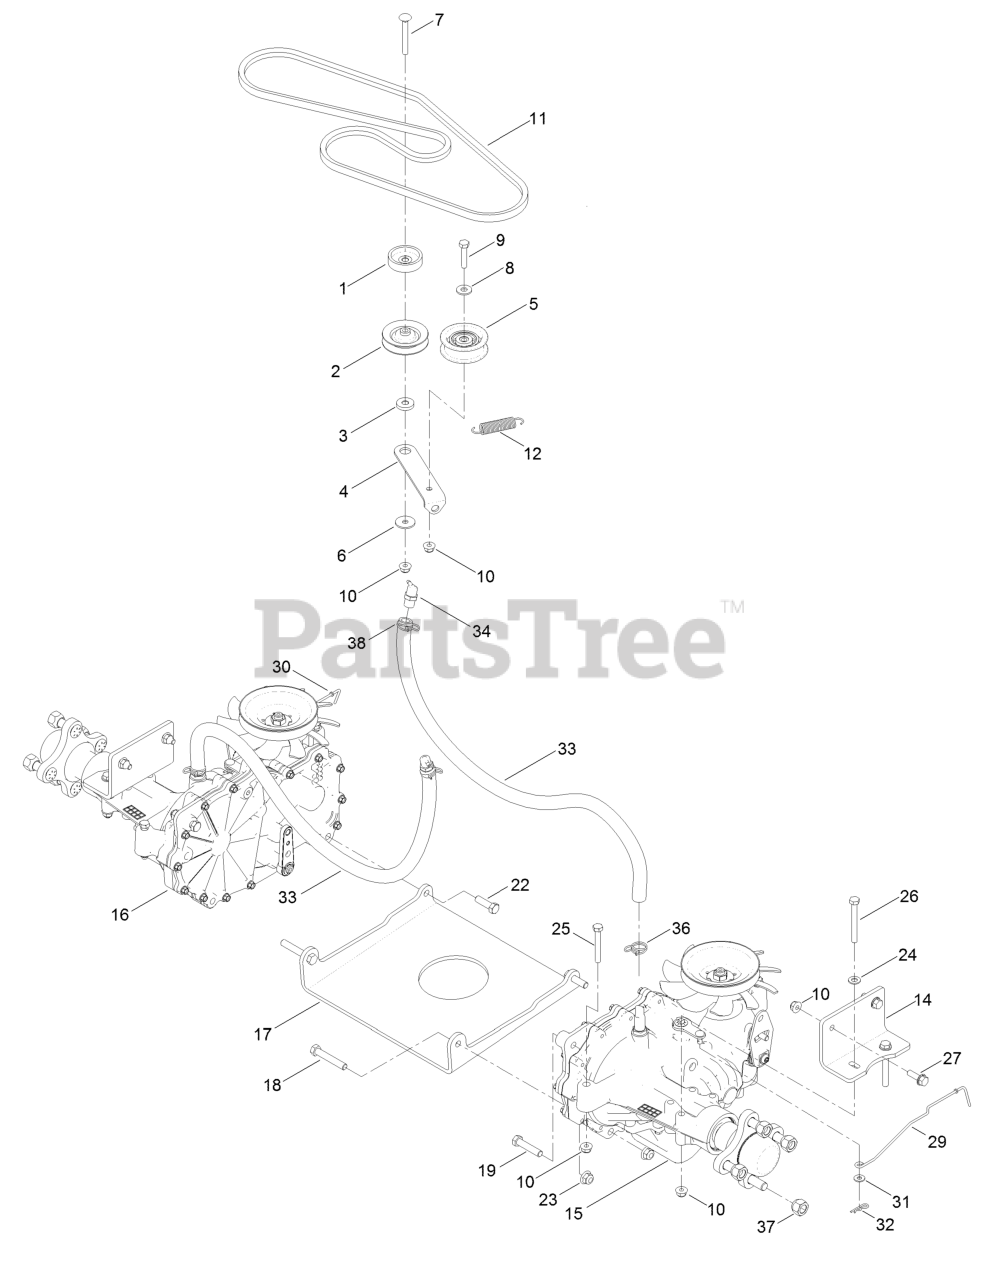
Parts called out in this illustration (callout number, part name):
2	Pulley-Idler
3	Spacer-Arm, Idler
4	Arm-Idler
5	Pulley-Idler
6	Washer-Pivot
7	Screw-CARR
8	Washer-Flat
9	Screw-HH
10	Nut-HF, NI
11	V-Belt
12	Spring-Return, Pedal
14	Mount-Hydro
15	LH Hydro Transmission ASM
16	RH Hydro Transmission ASM
17	Plate-Cross, Hydro
18	Screw-HH
19	Screw-HH
22	Screw-HH
23	Nut-HF, NI
24	Washer-Plain
25	Screw-HH
26	Screw-HH
27	Screw-HHF
29	Rod-Bypass, LH
30	Rod-Bypass, RH
32	Pin-Cotter
33	Hose-Hydro
34	Breather Kit
36	Clamp-Hose
37	Nut-Lug
38	Clamp-Hose
